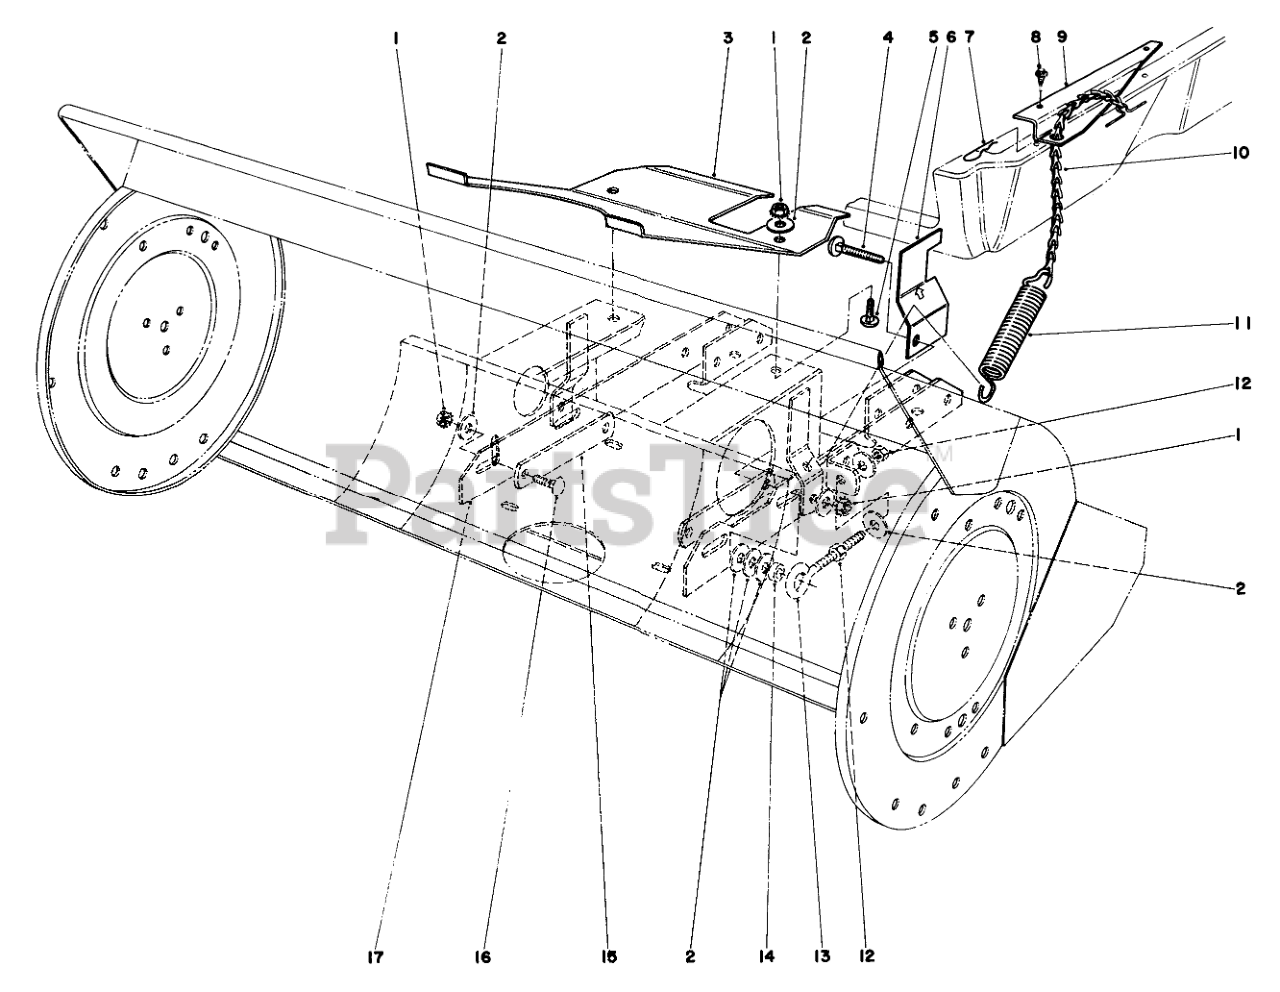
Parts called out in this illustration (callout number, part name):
1	NUT-KEPS
2	WASHER-FLAT
3	Guard-Drive Pulley
4	SCREW-CARR
5	SCREW-CARR
6	Bracket-Belt Adjust Guide
7	PIN-HAIR
8	SCREW-HWHTF
9	Plate-Lift Spring Anchor
10	CHAIN & TOGGLE ASM
11	IDLER ARM SPRING
12	NUT-HEX
13	Eye Bolt
14	Spacer
15	Strap-Header Channel
16	BOLT-CARR
17	Pivot Bracket
